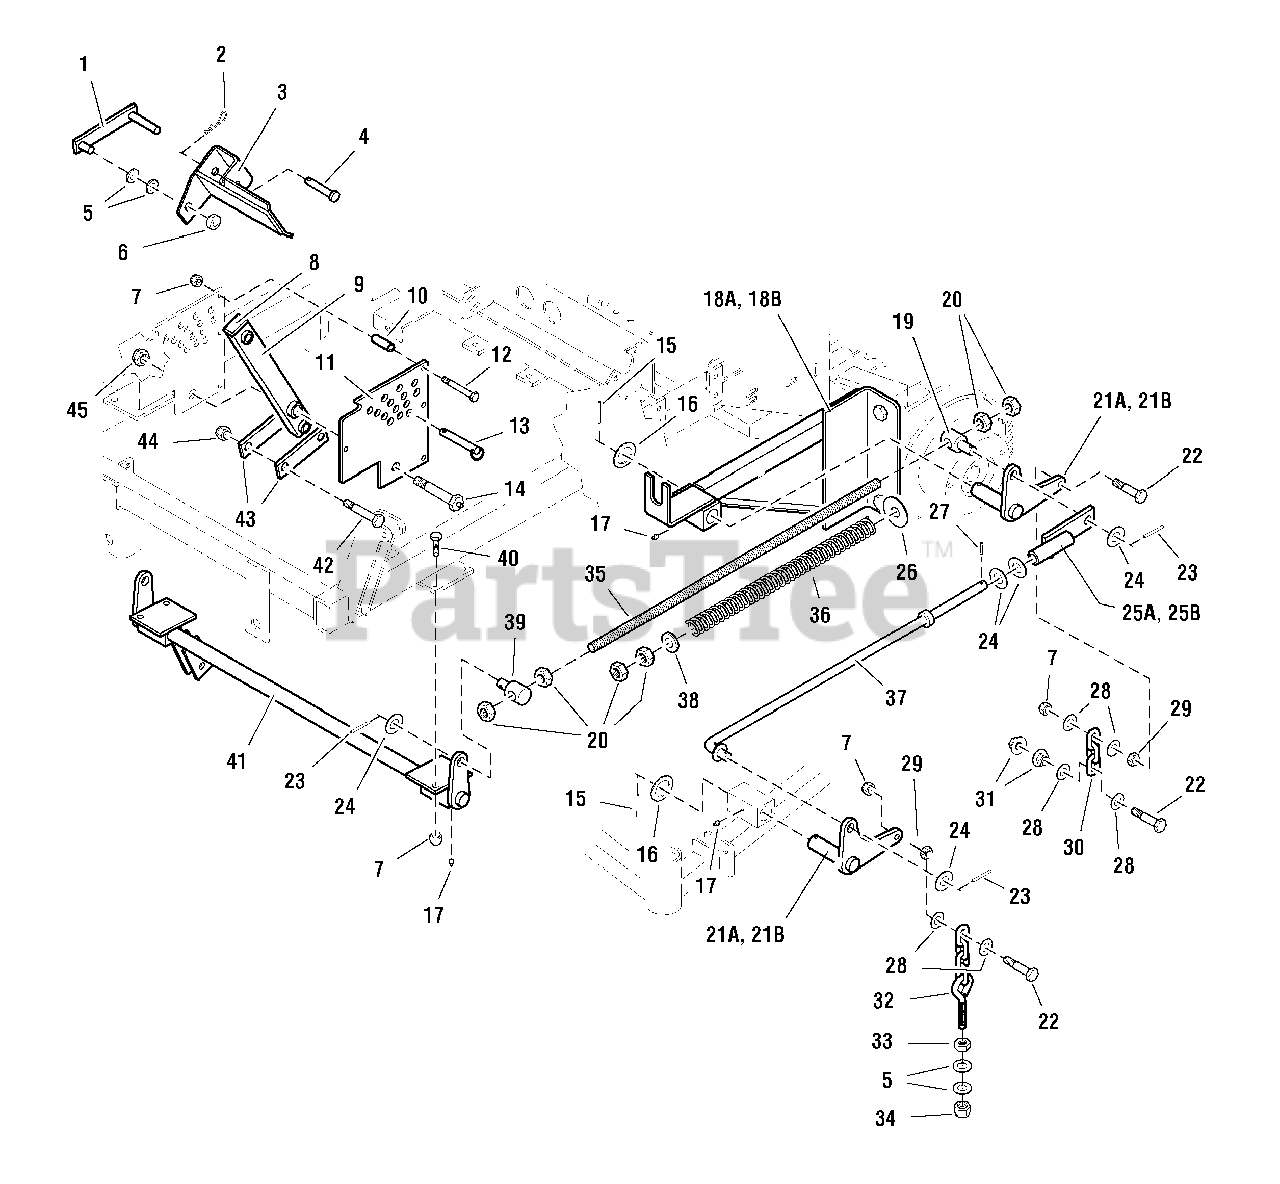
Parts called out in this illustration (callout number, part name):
1	DECK LIFT LOCK
2	HAIRPIN CLIP
3	DECK LIFT PEDAL
4	PIN, Clevis, 1/2 x 2-1/2
5	WASHER, 1/2
6	COLLAR, Split, 1/2
7	NUT, Hex, Nylon Lock, 3/8-16
9	DECK LIFT PIVOT ARM
10	SPACER, .38 x .50 x 1.56
11	DECK HEIGHT PLATE
12	CAPSCREW, Hex Hd, 3/8-16 x 2-3/4
13	PIN, 1/2 x 3
14	LIFT PIVOT BOLT
15	PIN, Roll, 3/16 x 1-1/2
16	SHIM WASHER
17	GREASE FITTING
18A	REAR DECK LIFT FRAME - LH
19	SPRING ROD PIVOT
20	NUT, Hex, 5/8-11
21A	DECK LIFT PIVOT - LH
22	CAPSCREW, Hex Hd, 3/8-16 x 1-3/4
23	PIN, Spring, 3/16 x 1-1/4
24	WASHER, 5/8
25A	DECK LIFT LINK - LH
26	WASHER, USS, 5/8
27	PIN, Roll, 3/16 x 3/4
28	WASHER, 3/8
29	NUT, Hex, Jam, 3/8-16
30	CHAIN, 3 Links
31	NUT, Hex, Serrated Flange, 3/8-16
32	HANGER, FRONT DECK - 4 LINK, 5.5" EB
33	NUT, Hex, 1/2-13
34	NUT, Hex, Nylon Lock, 1/2-13
36	SPRING, Deck Lift
37	DECK LIFT ROD
38	SPACER, .63 x 1.06 x .23
39	SPRING ROD PIVOT
40	CAPSCREW, Hex Hd, 3/8-16
41	DECK LIFT SHAFT & MOUNT ASSEMBLY
42	CAPSCREW, Hex Hd, 1/2-20 x 3
43	DECK LIFT LINK
44	NUT, Hex, Nylon Lock, 1/2-20
45	NUT, Hex, Jam, Nylon Lock, 5/8-11
